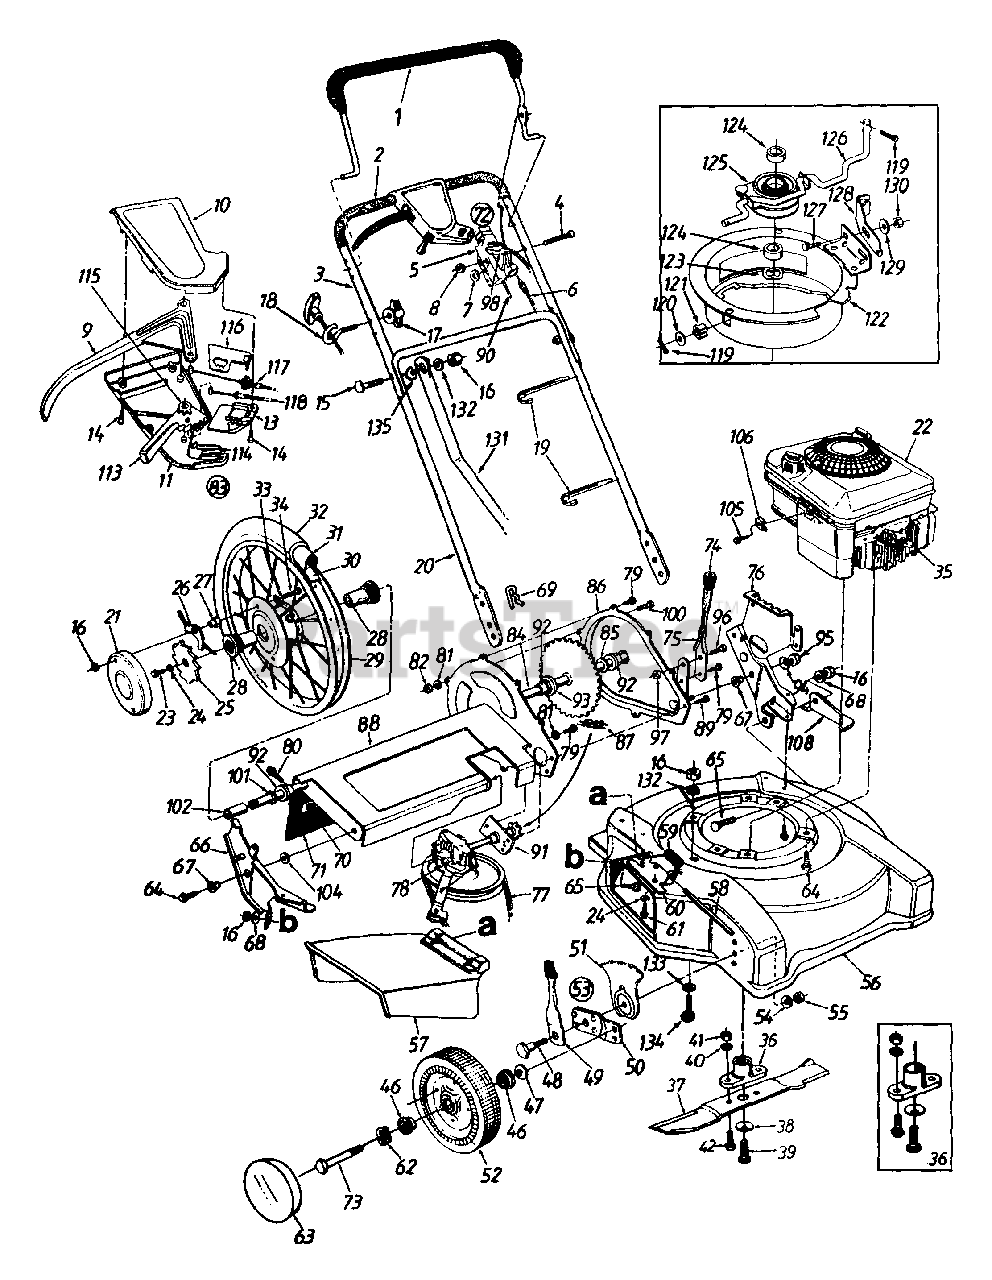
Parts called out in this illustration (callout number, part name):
1	Control Handle Ass'y.
2	Foam Grip
4	Oval C-Sunk Scr.
5	Throttle Body
6	Control Cable - 40.5" Lg.
7	Spring Wash. .66" I.D.
8	Hex L-Nut 1/4-20 Thd.
9	Control Lever
10	Control Cover Half - Upper
11	Control Cover Half - Lower
13	Cable Mounting Cap
14	Fl-"C" Sunk Hd. Tap Scr. #10 x .75" Lg.
15	Curved Hd. Bolt 5/16-18 x 2" Lg.
16	Hex Nut 5/16-18 Thd.
17	Handle Knob 1/4-20 Thd.
19	Cable Tie
22	Engine
23	Hex Bolt 1/4-20 x .75" Lg. (Gr. 5)
24	Bell-Wash. 1/4" I.D.
25	Wheel Ratchet
26	Pawl and Spring Ass'y.
27	Special Hex Nut 5/16-18 Thd.
28	Flange Bearing .63" I.D.
29	Rim Ass'y. Only 16" x 2.1"
30	Rimstrip 16" x 7/8"
31	Inner Tube 16" x 2.12"
32	Chevron Tire 16" x 2.125"
33	Intern. L-Wash. 5/16" I.D.
34	Hex Bolt 5/16-18 x 1.0" (Gr. 5)
35	Spark Plug Boot
36	Blade Adapter Kit
37	22" Blade
38	Bell-Wash. .39" I.D.
39	Hex Bolt 3/8-24 x 1.5" Lg.
40	L-Wash. 3/8" I.D.
41	Hex Nut 3/8-24 Thd.
42	Hex Bolt 3/8-24 x 1.0" Lg.
46	Ball Bearing 1/2" I.D.
47	Bell-Wash. .38" I.D.
48	Shld. Bolt .5"
49	Spring Lever Ass'y. w/Knob
51	Height Adj. Plate
52	Wheel Ass'y. Comp.
53	Height Adj. Ass'y. Comp. - R.H.
54	Bell-Wash. .39" I.D. x 1.38"
55	Hex Nut 3/8-16 Thd.
58	Hinge Pin
59	Torsion Spring
60	Adapter Plate
61	Hex TT-Tap Scr. 1/4-20 x .5"
62	Wave Wash. .51" I.D. x .78"
64	Hex TT-Tap Scr. 3/8-16 x 1"
65	Carriage Bolt 5/16-18 x .62" Lg.
68	Bell-Wash. 5/16" I.D.
69	Intern. Cotter Pin 5/16" Dia.
70	Retaining Strip
72	Throttle Box Comp.
73	Front Axle Bolt
75	Height Adjustment Lever
78	Transmission Comp.
79	Hex B-Tap Scr. 1/4 x .38" Lg.
80	Hex AB-Tap Scr. 1/4 x .62" Lg.
81	L-Wash. 1/4" I.D.
82	Hex Nut 1/4-20 Thd.
83	Wheel Ass'y. Comp.
84	Sprocket and Axle Ass'y.
85	Fl-Wash. .635" I.D. x 1.0" O.D.
90	Throttle Cable - 61" Lg.
92	Hex Flange Brg. .631" I.D.
93	Spacer .63" I.D. x 1.25"
94	Fl-Wash. .385" I.D. x .87" O.D.
95	Hex L-Nut 3/8-24 Thd.
96	Hex Bolt 3/8-16 x .62" Lg.
97	Flanged L-Nut 3/8-16 Thd.
98	Throttle Lever
100	Hex Bolt 1/4-20 x .5" Lg.
101	Fl-Wash. .632" I.D. x .943"
102	Spacer .628" I.D. x .875"
104	Fl-Wash. .38" I.D. x 1" O.D.
105	Wash. Hd. Scr. #10-32 x .62" Lg.
106	Casing Clamp
108	Deck Bracket
113	6-Spd. Shift Lever
114	Shift Lever Spring
115	3-Tooth Rack Gear Insert
116	6-Speed Rack Cable Brkt.
117	S.P. Cable
118	Spd. Control Cable - 50" Lg.
119	Cotter Pin 3/32" Dia.
120	Fl-Wash. .33" I.D. x .687" O.D.
121	Flanged Bushing
124	Spacer .885" I.D. x 1" O.D.
125	Pulley Ass'y.
127	Carr. Bolt 1/4-20 x .5" Lg.
130	Hex L-Nut 1/4-20 Thd.
133	Fl-Wash. 7/16" I.D. x 7/8" O.D.
134	Carriage Bolt 5/16-18 x .62" Lg.
135	Saddle Wash. .32" I.D. x .93"
